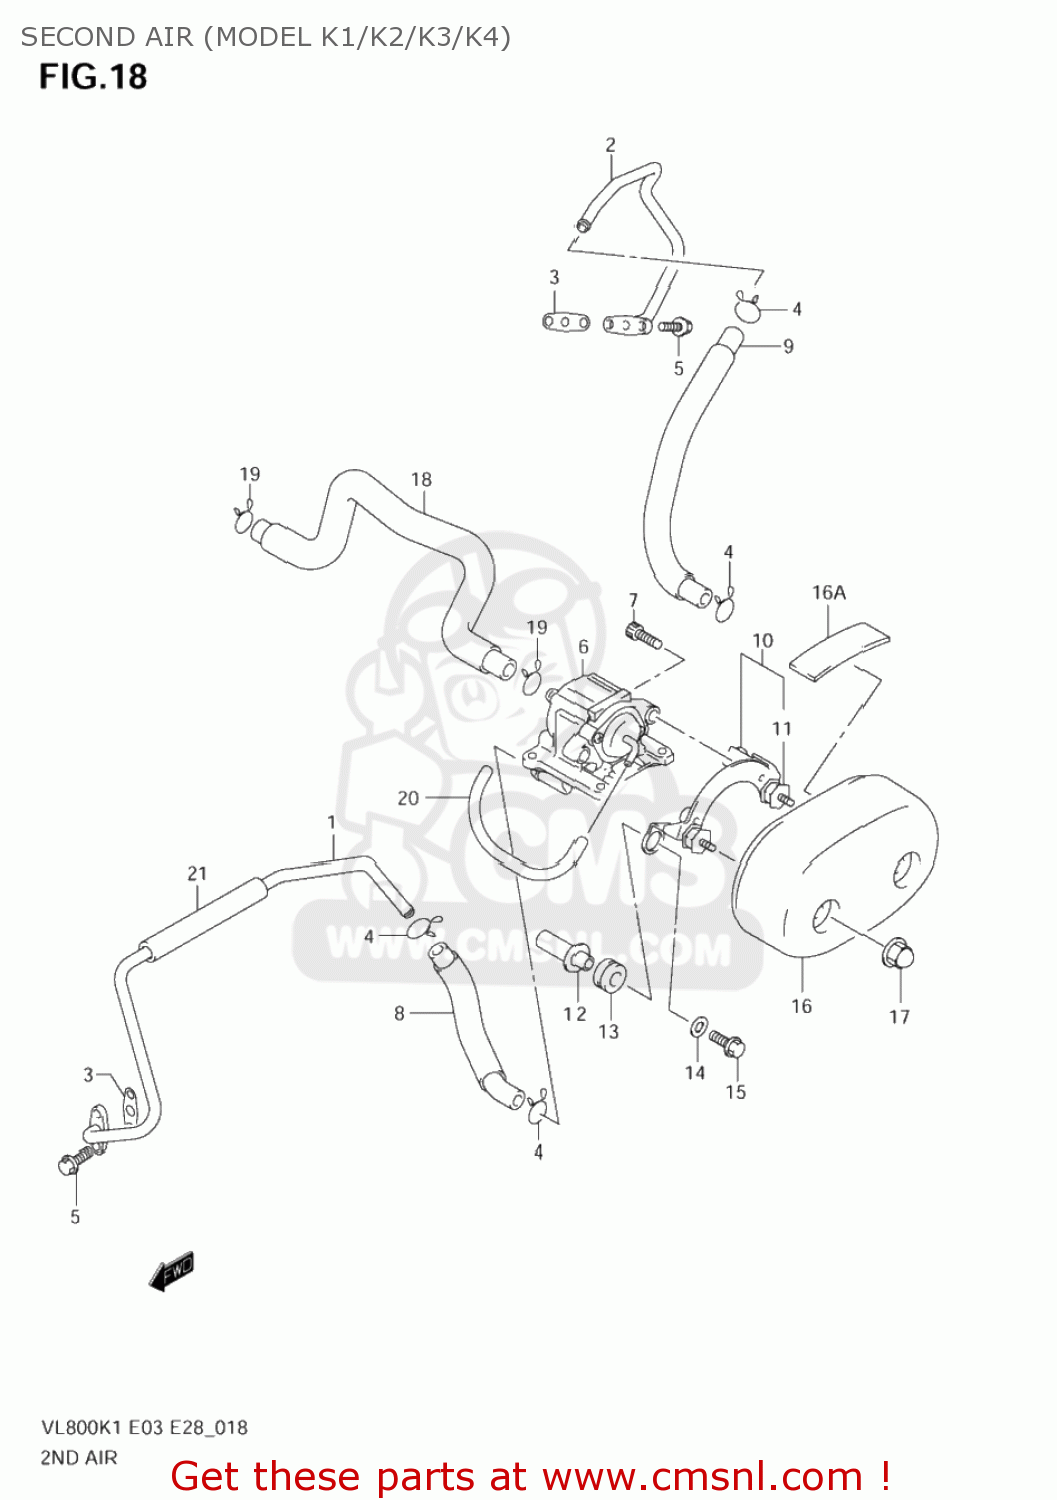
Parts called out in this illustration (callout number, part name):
1	PIPE,2ND AIR FR
2	PIPE,2ND AIR RR
3	GASKET,2ND AIR PIPE (NAS)
4	CLIP
5	BOLT
6	VALVE ASSY,2ND
7	BOLT,CRKCASE,R
8	HOSE,2ND AIR VALVE FR
9	HOSE,2ND AIR VALVE RR
10	BRACKET,2ND AIR SPRT
11	BOLT,2ND AIR COV
12	SPACER,2ND AIR SPRT BRKT
13	CUSHION
14	WASHER(6.5X20X1)
15	BOLT, HYDRAULIC UNIT NO.2
16	COVER,2ND AIR
16A	SHEET,2ND AIR COVER
17	NUT
18	HOSE,2ND AIR CLEANER
19	CLIP
20	HOSE(3.5X7.5X600)
21	PROTECTOR,2ND AIR PIPE FR
